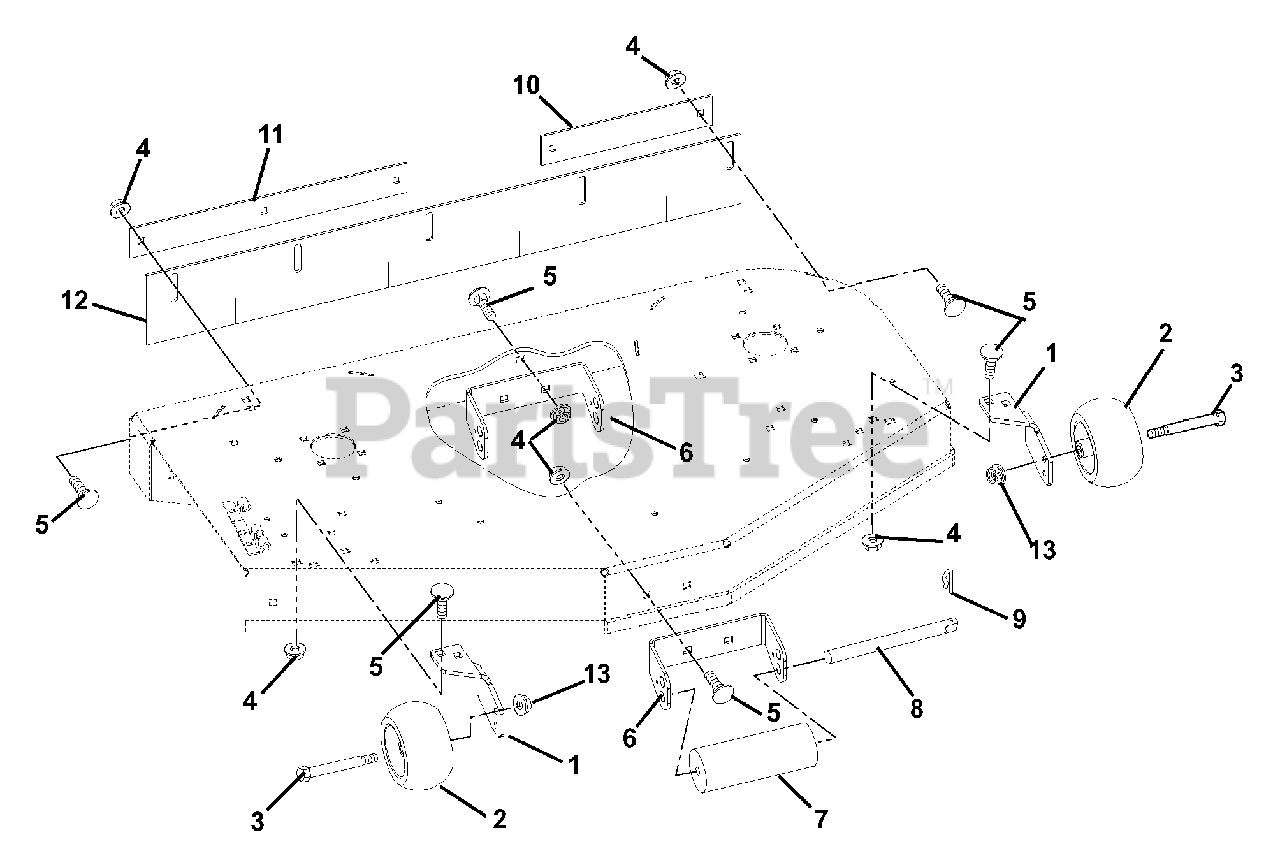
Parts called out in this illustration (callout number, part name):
1	BRACKET, ANTI SCALP
2	WHEEL 5 X 3
3	BLT-SHLDR .38-16X2.50 HWH G5
4	@NUT-LK-NYL-FLG .38-16 YWZC
5	@BLT-RDHDSQNK .38-16X1.00 G5YZ
6	BRACKET, ROLLER MOUNT
7	ROLLER
8	PIN, ROLLER
9	PIN, SPRING CLIP
10	BAR, LH RETAINER STRIPER
11	BAR, RETAINING STRIPER-44"
11	BAR, RETAINING STRIPER-52"
11	BAR, RETAINING STRIPER-40"
12	STRIPER, RUBBER-44"
12	STRIPER, RUBBER-48"
12	STRIPER, RUBBER-52"
12	STRIPER, RUBBER-40"
13	@NUT-LK-TOP-FLG .38-16 YWZC
